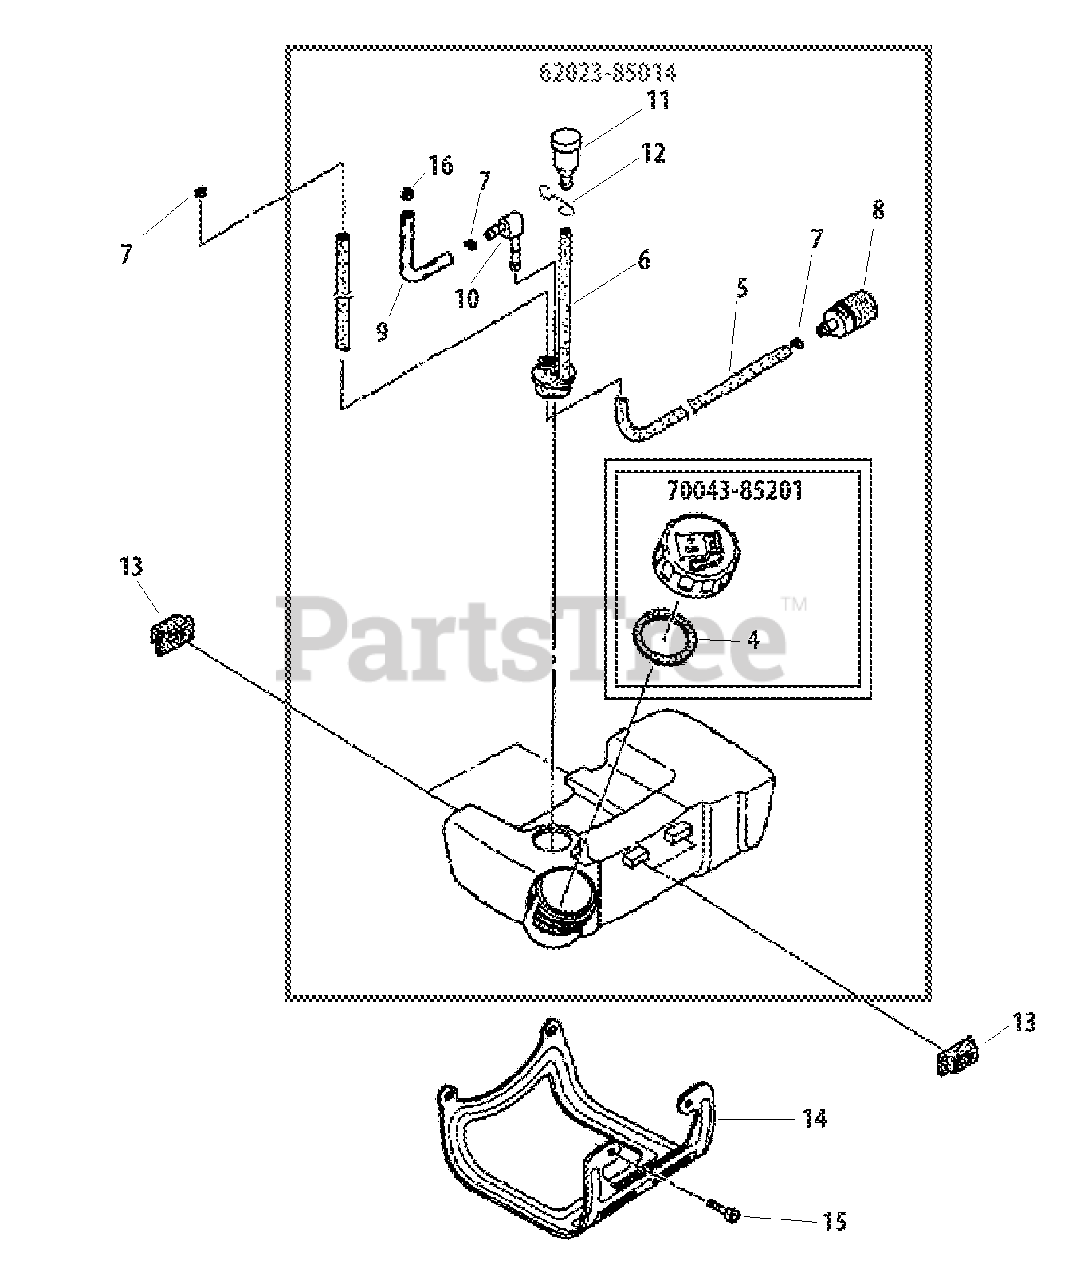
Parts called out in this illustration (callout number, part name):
4	GASKET, FUEL CAP
5	PIPE, FUEL
6	GROMMET, FUEL W/VENT PIPE
7	CLIP Ø6
8	FILTER, FUEL 125-528
9	PIPE, FUEL RETURN
10	CONNECTOR, PIPE
11	VENT ASSY
12	CLIP, VENT ASSY
13	CUSHION, FUEL TANK
14	GUARD, METAL FUEL TANK
15	BOLT M5×12
16	CLIP, SPRING Ø5.2
62023-85014	FUEL TANK ASSY
70043-85201	CAP ASSY, FUEL
